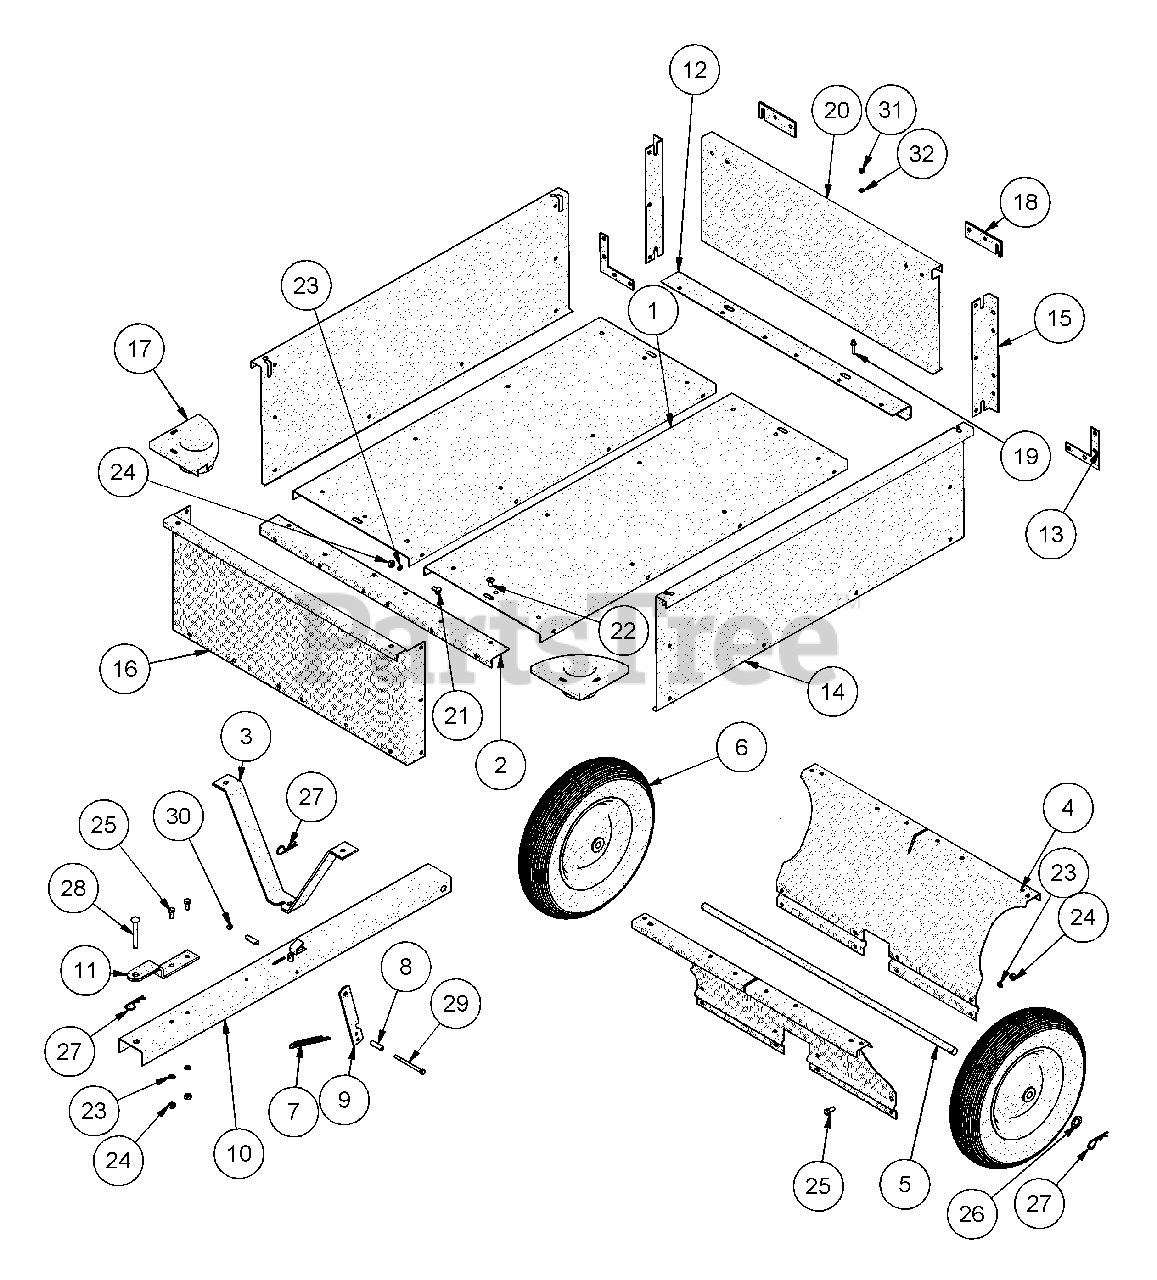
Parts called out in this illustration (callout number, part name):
1	BOTTOM PANEL
2	FRONT CROSS BRACE
3	TONGUE SUPPORT
4	WHEEL AXLE SUPPORT
5	WHEEL AXLE
6	WHEEL/TIRE ASSEMBLY
7	LATCH SPRING
8	LATCH SPACER
9	TONGUE LATCH
10	HITCH TONGUE
11	HITCH PIN BRACKET
12	REAR CROSS BRACE
13	REAR CORNER BRACKET
14	SIDE PANEL
15	REAR CORNER BRACE
16	FRONT PANEL
17	FRONT CORNER BRACE
18	TAILGATE LATCH
19	TAILGATE PIN
20	TAILGATE
21	M8 X 16 TRUSS HEAD BOLT
22	M8 X 20 TRUSS HEAD BOLT
23	8MM LOCK WASHER
24	8MM HEX NUT
25	M8 X 20 HEX BOLT
26	20MM FLAT WASHER
27	3MM HAIRPIN
28	HITCH PIN
29	M6 X 90 HEX BOLT
30	6MM NYLON NUT
31	6MM HEX NUT
32	6-8MM FLAT WASHER
